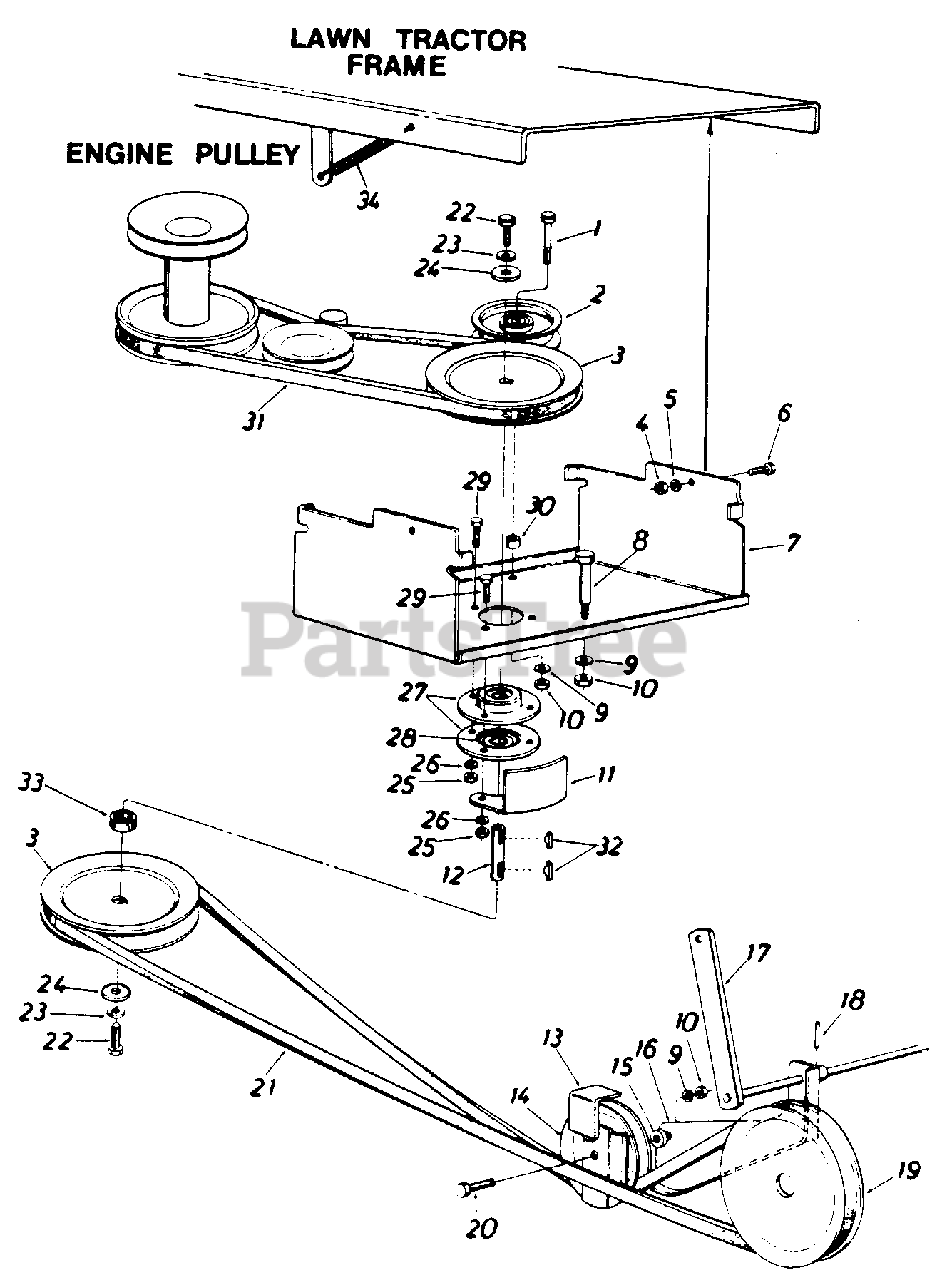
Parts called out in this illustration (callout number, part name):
1	Hex Bolt 3/8-16 x 2" Lg.
2	FL-Idler w/Flanges 3-3/4" O.D.
3	5/8" "V"-Pulley .79" I.D. x .65" O.D.
4	Hex Nut 3/8-24 Thd.
5	L-Wash. 3/8" I.D.
6	Hex Bolt 3/8-24 x .88" Lg.
9	L-Wash. 3/8" I.D.
10	Hex Nut 3/8-16 Thd.
13	Belt Separator Plate
14	Fl-Idler w/Flanges 3 25"
15	Fl-Wash. 406" I.D. x 1.25"
18	Spring Pin Roll 3/16" Dia.
19	5/8" V-Pulley 1.50" I.D. x 6.5 O.D.
20	Hex Bolt 3/8-16 x 1.75" Lg.
21	"V"-Belt
22	Hex Bolt 5/16-18 x .88" Lg. Spec.
23	L-Wash. 5/16" I.D.
24	Fl-Wash. .344" I.D. x 1.125"
25	Hex Nut 5/16-18 Thd.
26	L-Wash. 5/16" I.D.
27	Bearing Housing 1.85" I.D.
28	Ball Bearing 1.85" O.D.
29	Hex Sems Bolt 5/16-18 x .75"
30	Spacer
31	Belt
32	Hi-Pro Key 3/16" x 518"
33	Spacer .66" I.D. x 1" O.D.
34	Extension Spring
